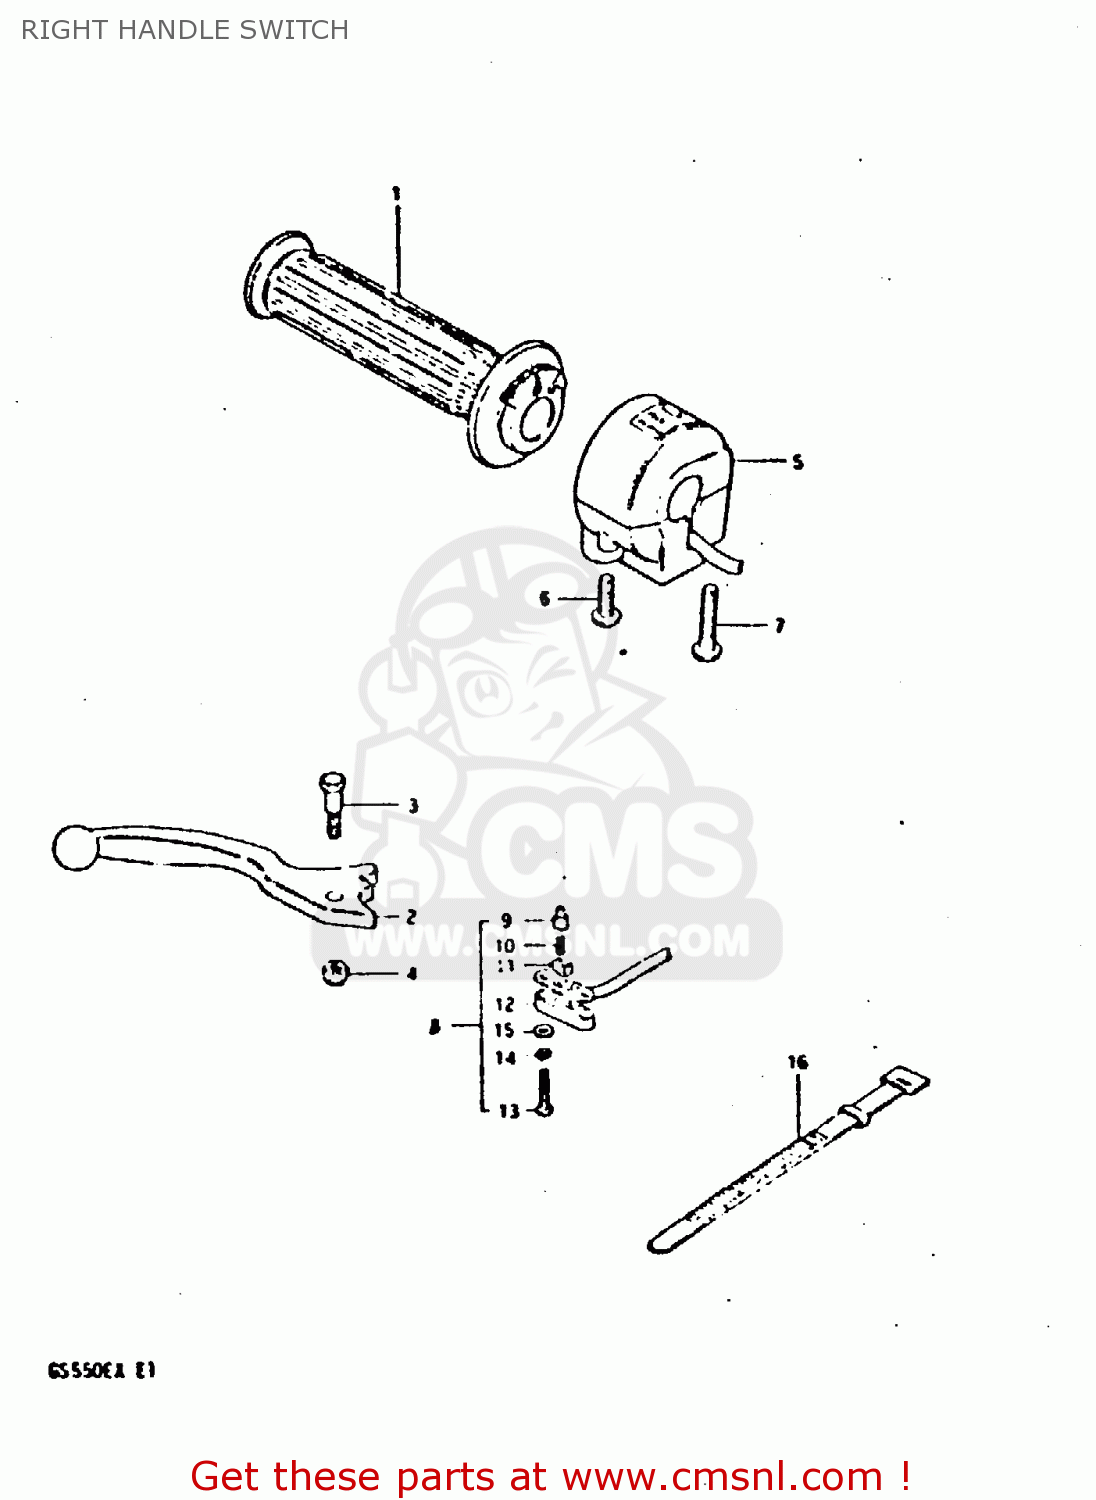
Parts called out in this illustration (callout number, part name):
1	GRIP,THROTTLE
2	LEVER,BRAKE
3	BOLT
4	NUT 6MM
5	SWITCH ASSY, HANDLE RH
6	SCREW
7	SCREW
16	CLAMP(L:120)
